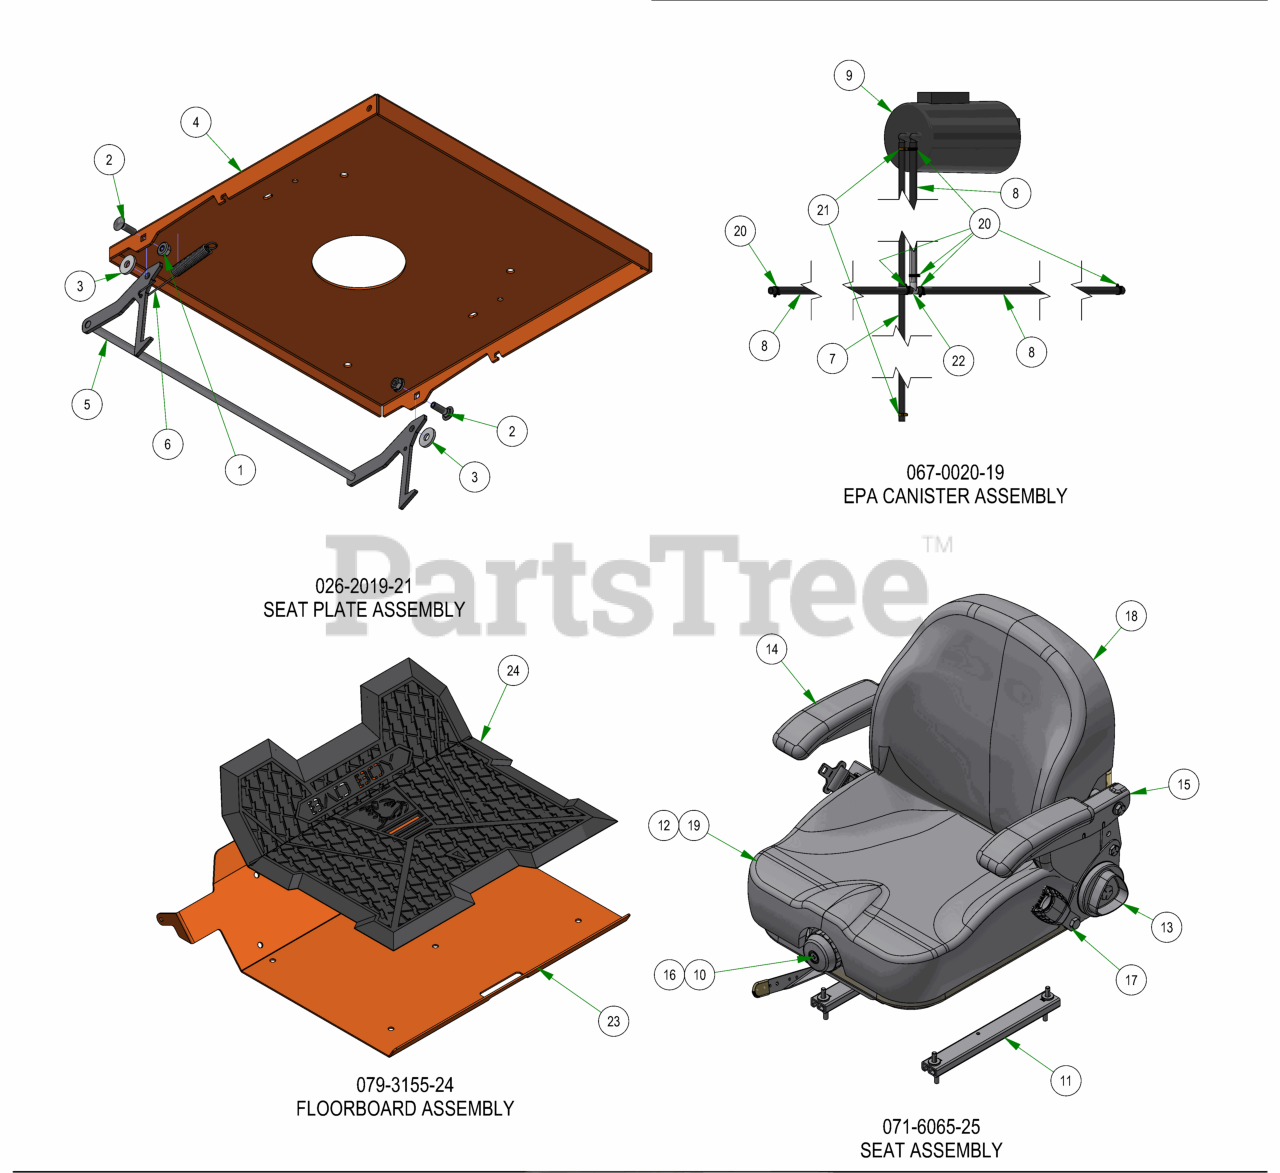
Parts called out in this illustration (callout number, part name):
1	5/16-18 NYLON INSERT FLANGE LOCKNUT ZINC
2	5/16-18 X 1 CARRIAGE BOLT (GR.8) ZINC
3	.360 ID X .983 OD X .120 THICK FLAT WASHER NYLON
4	R-SERIES SEAT PLATE
5	Seat Latch Rod Assembly
6	Brake Spring
7	3/16" Vinyl Tubing, 66" Long
8	1/4" Vinyl Tubing 38" Long
9	Carbon Canister
10	Weight Adjust Indicator Knob Assy
11	4" Single Locking Track Kit
12	Delta Plunger Switch - N.O.
13	Recliner Adjustment Knob-New
14	RH Armrest-Selfskin Front Adj
15	LH Armrest-Selfskin Front Adj
16	Bellows w/Hardware
17	2" Retractable Belt Kit w/Spacers
18	Back Cover, 2025 Suspension Seat
19	Cushion Cover, 2025 Suspension Seat
20	3/16 Vinyl Clamp
21	3/16" Vinyl Hose Clamp
22	fuel line T
23	2024 R-Series Floorboard
24	24 R-Series Floorboard Matt v2
